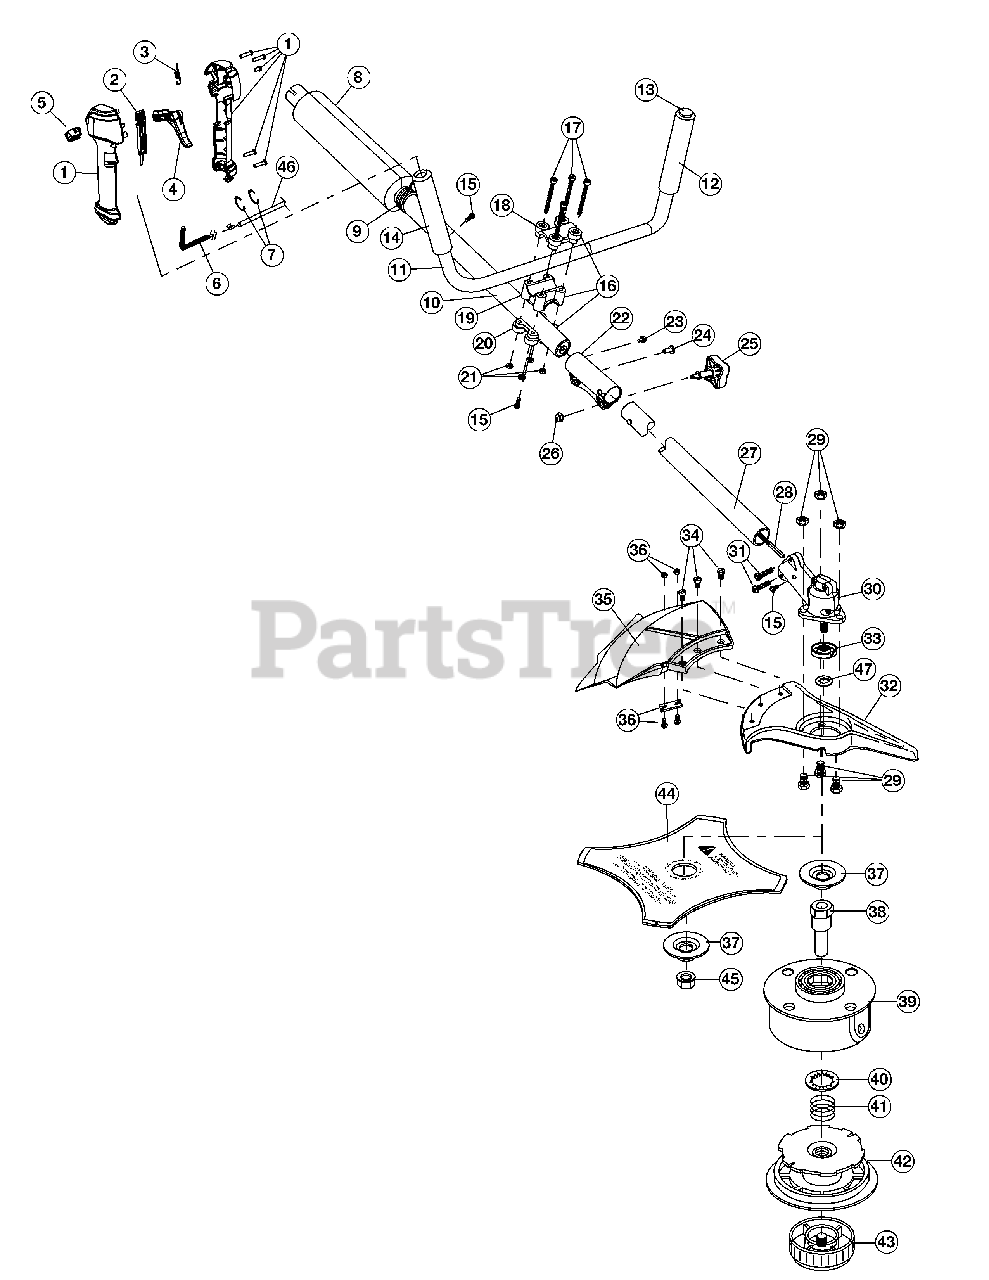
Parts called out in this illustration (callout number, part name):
1	Throttle Housing Assembly (Incl. 2 - 5)
2	Throttle Trigger Lock-Out
3	Throttle Trigger Spring
4	Throttle Trigger
5	Switch Assembly
6	Wire Cover 1ft
8	Foam Grip & Cover
9	Harness Clip
10	Upper Drive Shaft Housing Assembly
11	Bullhorn Handle Assembly (Incl. 12 - 15)
13	Tube Closure
14	Adapter
15	Anti-Rotation Screw
16	Handle Bracket Assembly (Incl. 17 - 21)
18	Upper Handle Clamp
19	Middle Handle Clamp
20	Lower Handle Clamp
22	Split Boom Coupler (Incl. 23 - 26)
25	Adjustment Knob
26	Knob Retaining Nut
27	Lower Drive Shaft Housing
28	Lower Flexible Drive Shaft
29	Shield Mount Screw Assembly
30	Gearbox Assembly (Incl. 15, 31, 33 & 47)
31	Gear Box Screw
32	Blade Shield/Shield Mount
33	Blade Driver
34	Shield Mounting Screw
35	Shield Assembly (Incl. 36)
36	Blade Assembly
37	Retaining Washer
38	Spool Shaft
39	Outer Spool Assembly
40	Retainer
43	Bump Head Knob Assembly
44	4-Tooth Blade
46	Throttle Cable
